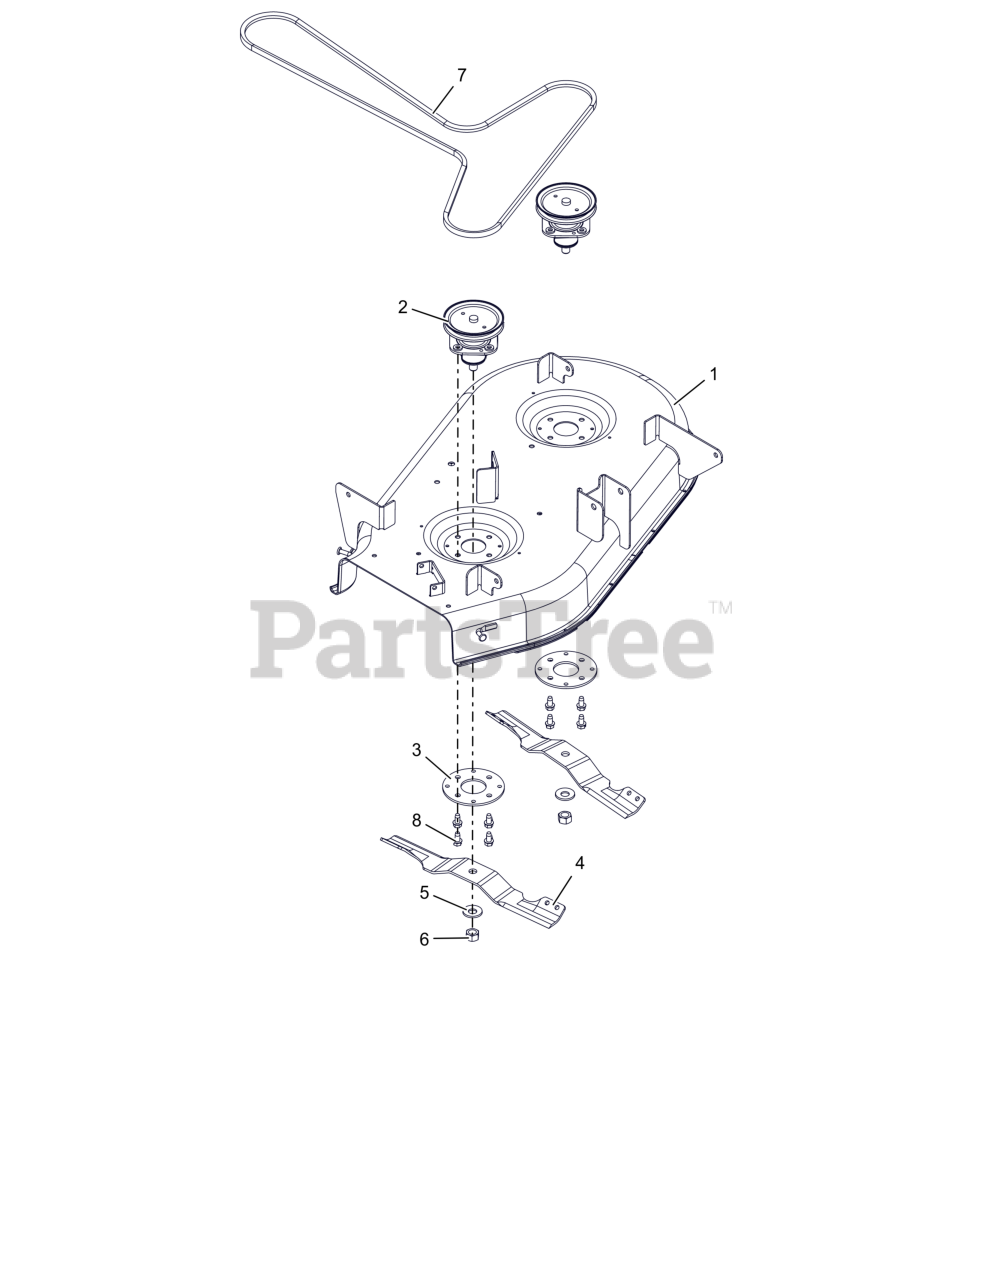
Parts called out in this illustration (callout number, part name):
1	KIT, 34" ZT DECK W/DECALS
2	KIT, DECK SPINDLE ASM (34/50)
3	PLATE-REINF, SPINDLE
4	BLADE, MOWER 17.35
5	WSHR-BLVL .669X1.535X.138
6	NUT-STD .625-18 ZCC
7	V-BELT, HA-WRAPPED
8	SCR,TAP .375-16X.75 HWH TR ZCC
